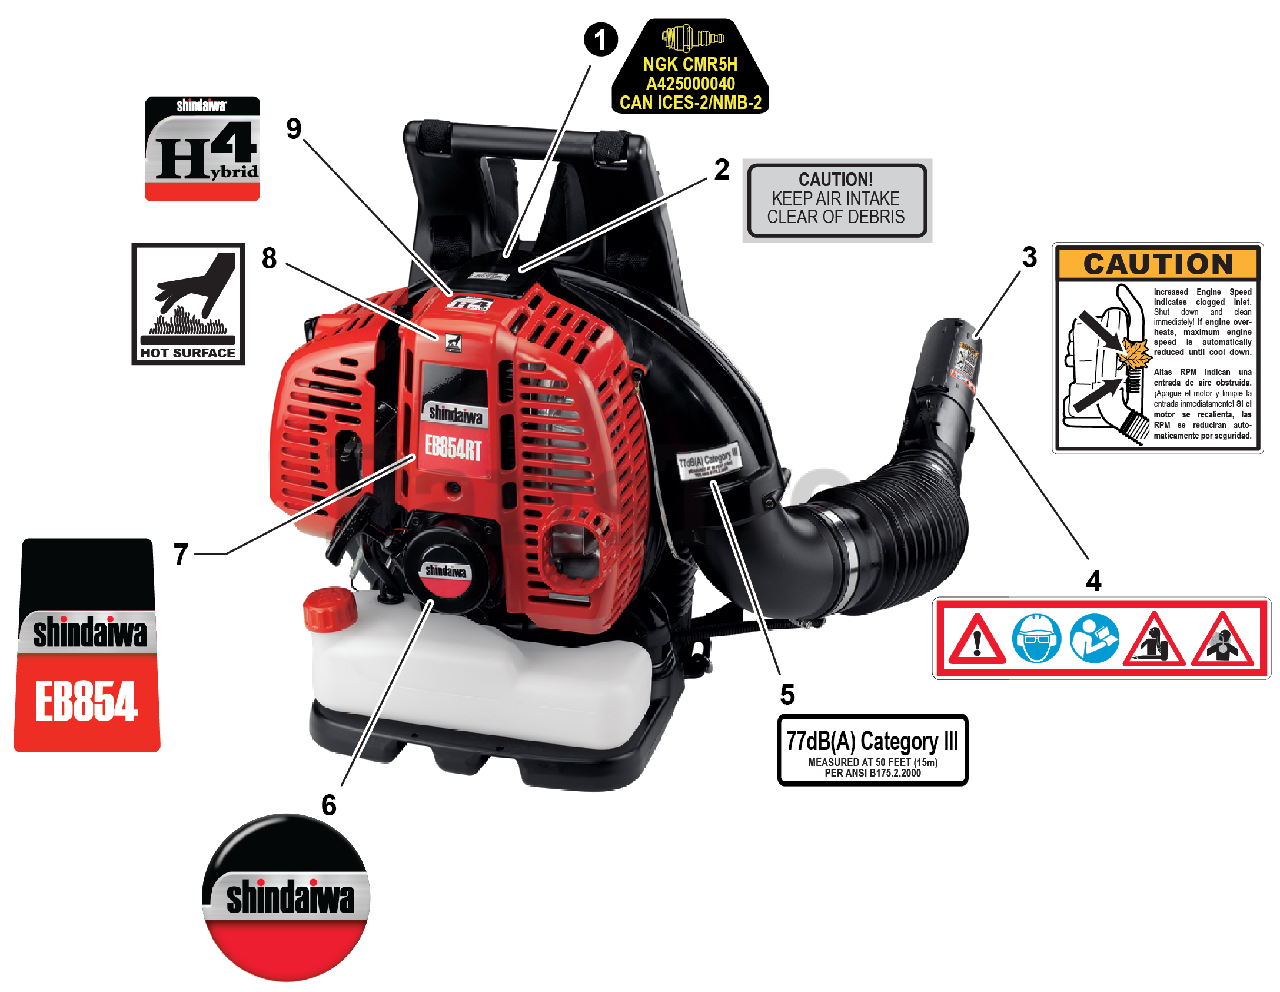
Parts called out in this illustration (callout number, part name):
1	LABEL, SPARK PLUG - CMR5H
2	LABEL, CAUTION - AIR INTAKE
3	LABEL, CAUTION - CLOGGED INLET
4	LABEL, CAUTION
5	LABEL, NOISE 77DB(A)
6	LABEL, RECOIL STARTER
7	LABEL - MODEL EB854
8	LABEL, CAUTION - HOT
9	LABEL, SHINDAIWA H4
